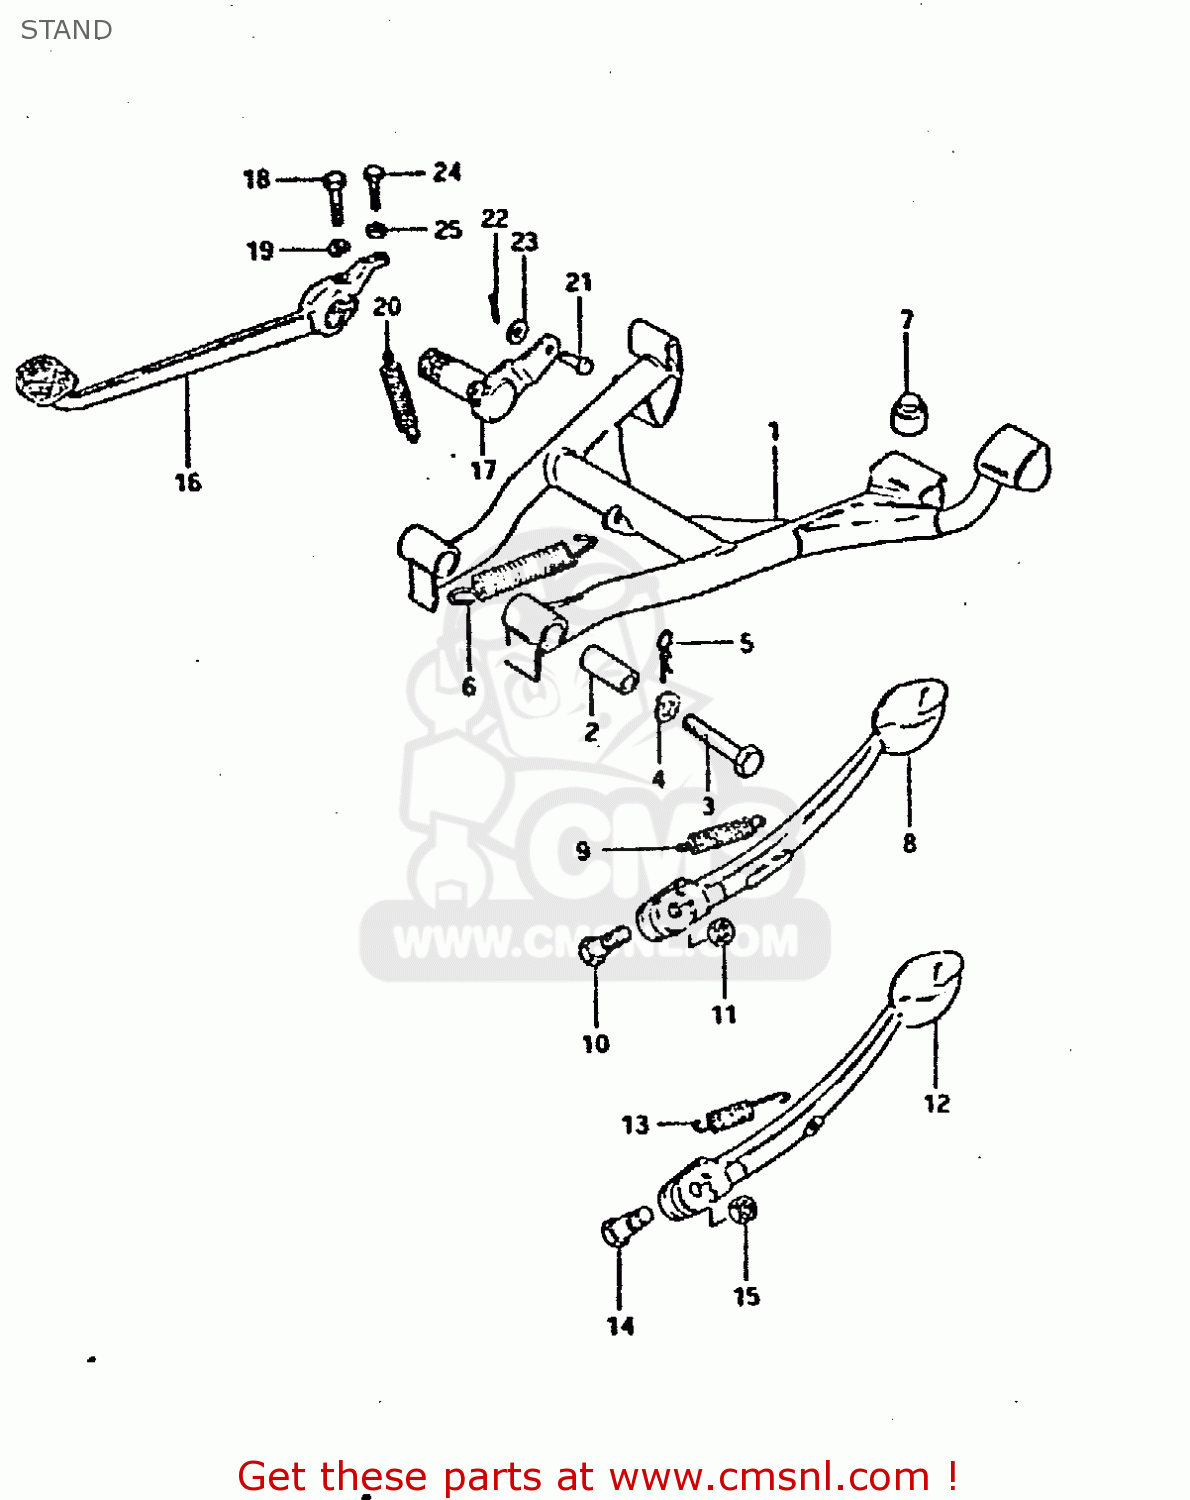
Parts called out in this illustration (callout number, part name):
1	STAND,CENTER
2	SPACER(10X16X38.8)
3	BOLT
4	LOCK WASHER
5	CLIP
6	SPRING
7	CUSHION
8	STAND,SIDE
9	SPRING
10	BOLT(10X30)
11	NUT
16	PEDAL,BRAKE
17	ARM,BRAKE PEDAL ROD
18	BOLT
19	LOCK WASHER
20	SPRING
21	PIN
22	PIN
23	WASHER
24	BOLT
25	NUT
